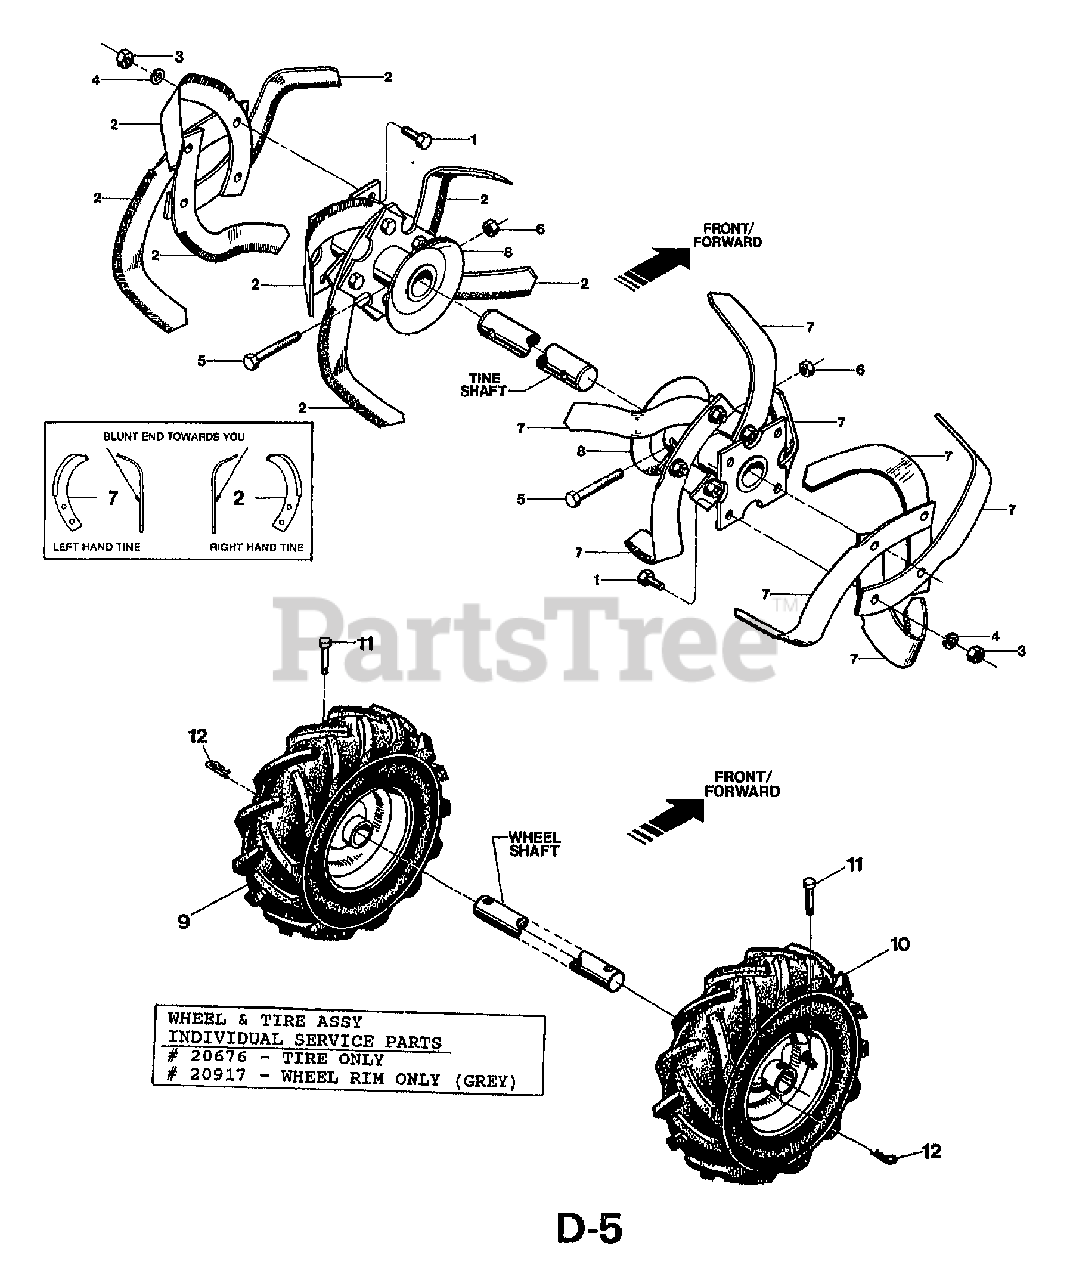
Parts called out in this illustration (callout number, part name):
1	SCR-HH 3/8-16X1.0 G5 ZP
2	TINE-BOLO RT W/HDW
3	NUT-HEX 3/8-16 ZP
4	WASHER-LK .375 @ DEPL
5	SCR-HH 3/8-16X2.00 G8
6	NUT-H/LK 3/8-16
7	TINE-BOLO LT W/HDW
8	HOLDER-TINE PONY
9	ASSM-TIRE&WHL LH GRAY
9	ASSM-TIRE LT 4.10 X 6"
10	ASSM-TIRE&WHL RH GRAY
10	ASSM-TIRE RT 4.10 X 6"
11	PIN-CLEVIS
12	PIN-CLIP .08
